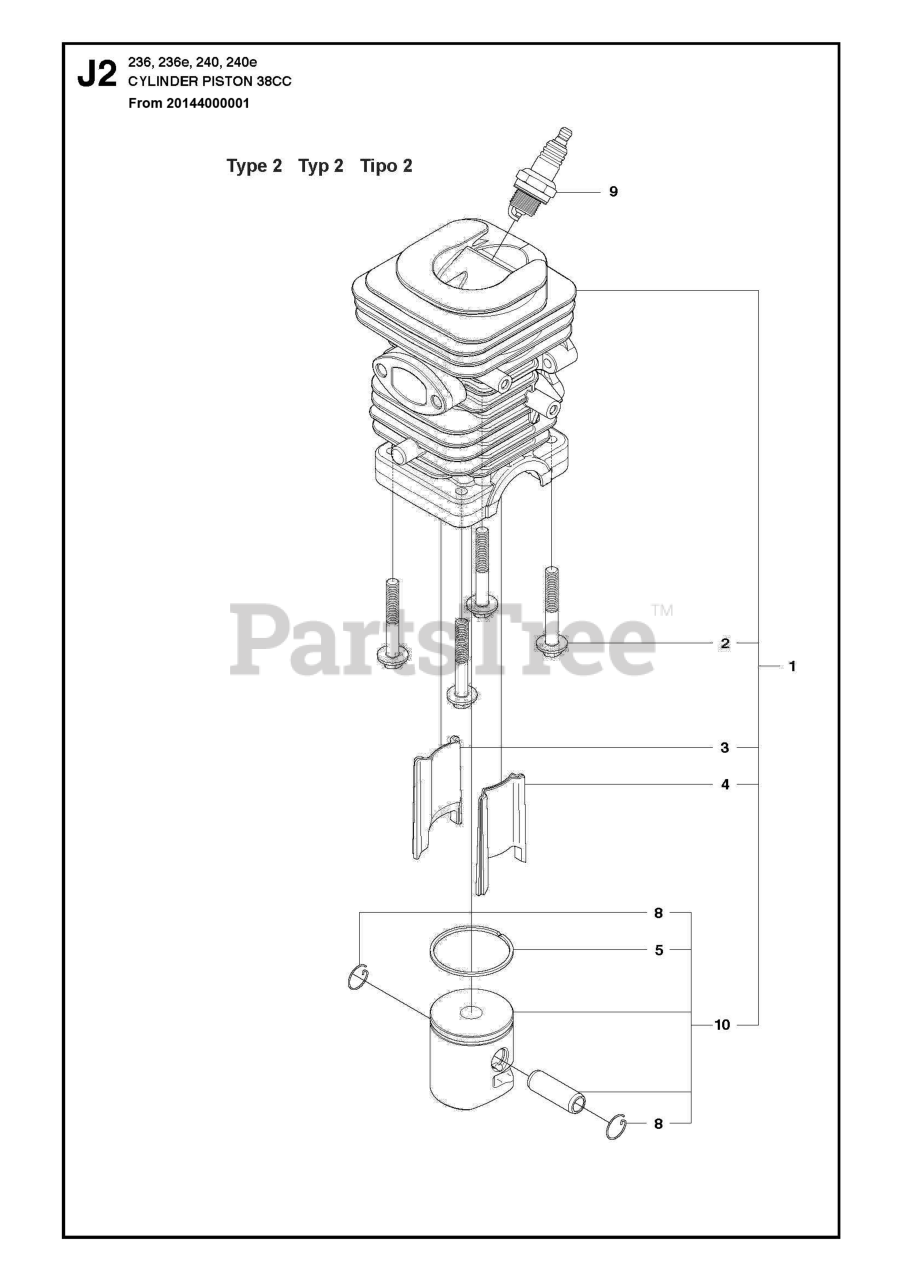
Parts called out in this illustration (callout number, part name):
1	Pistons
3	CYLINDER INSERT LEFT 38CC
4	CYLINDER INSERT RIGHT 38CC
5	PISTON RING 38CC
8	C-CLIP,PSTN PIN 36/41
9	SPARK PLUG RCJ7Y
10	PISTON KIT
